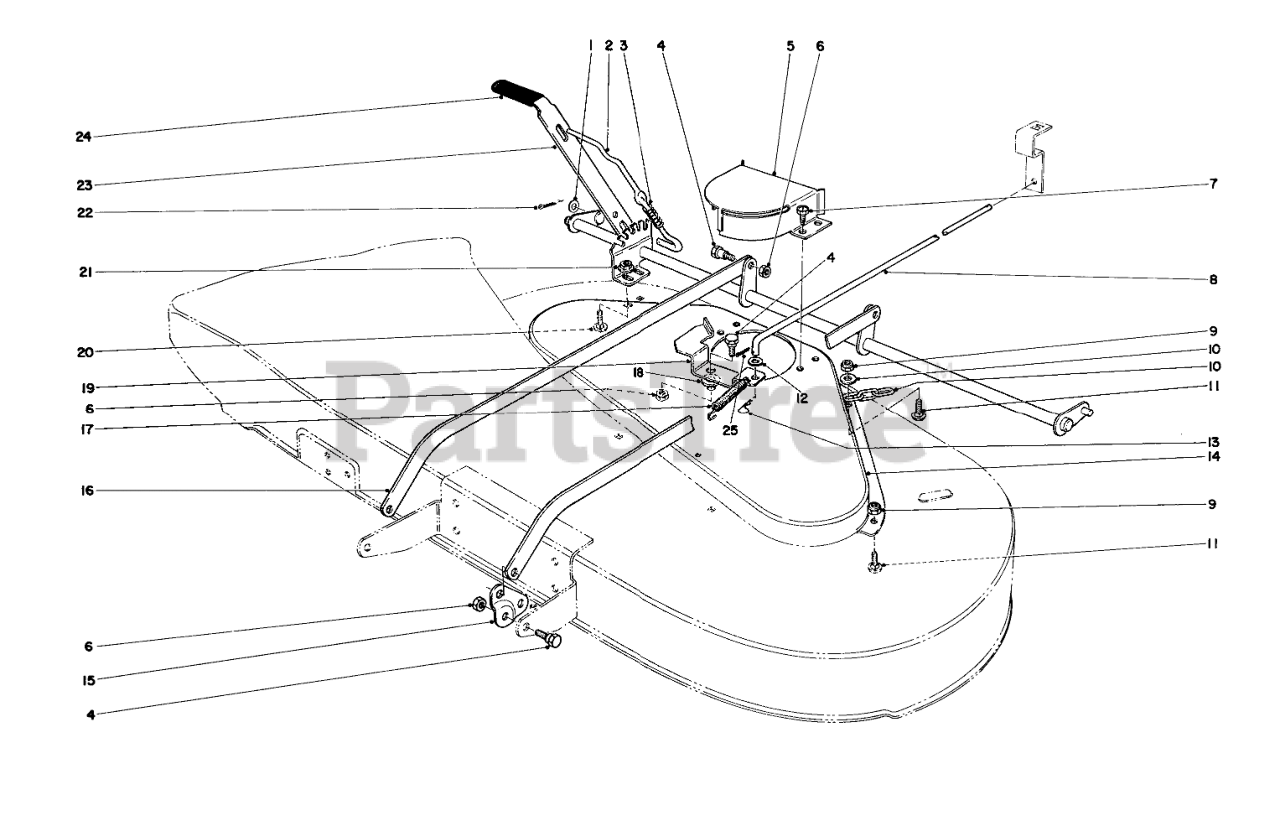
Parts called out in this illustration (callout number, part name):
1	WASHER-FLAT
2	Latch Slide
3	Spring
4	Screw
5	Cover Pulley
6	NUT-LOCK, CONE
7	SCREW-HWH
8	Blade Brake Rod
9	NUT-LOCK, CONE
10	Chain
11	SCREW-CARR
12	WASHER-PLAIN
13	PIN-COTTER
14	Pulley Cover
15	Blade Housing Pivot
16	Parallel Bar
17	Spring
18	Washer
19	Blade Brake Lever
20	BOLT-CARR
21	NUT-HF
22	PIN-COTTER
23	Shaft Assembly
24	Grip Handle
25	PIN-COTTER
